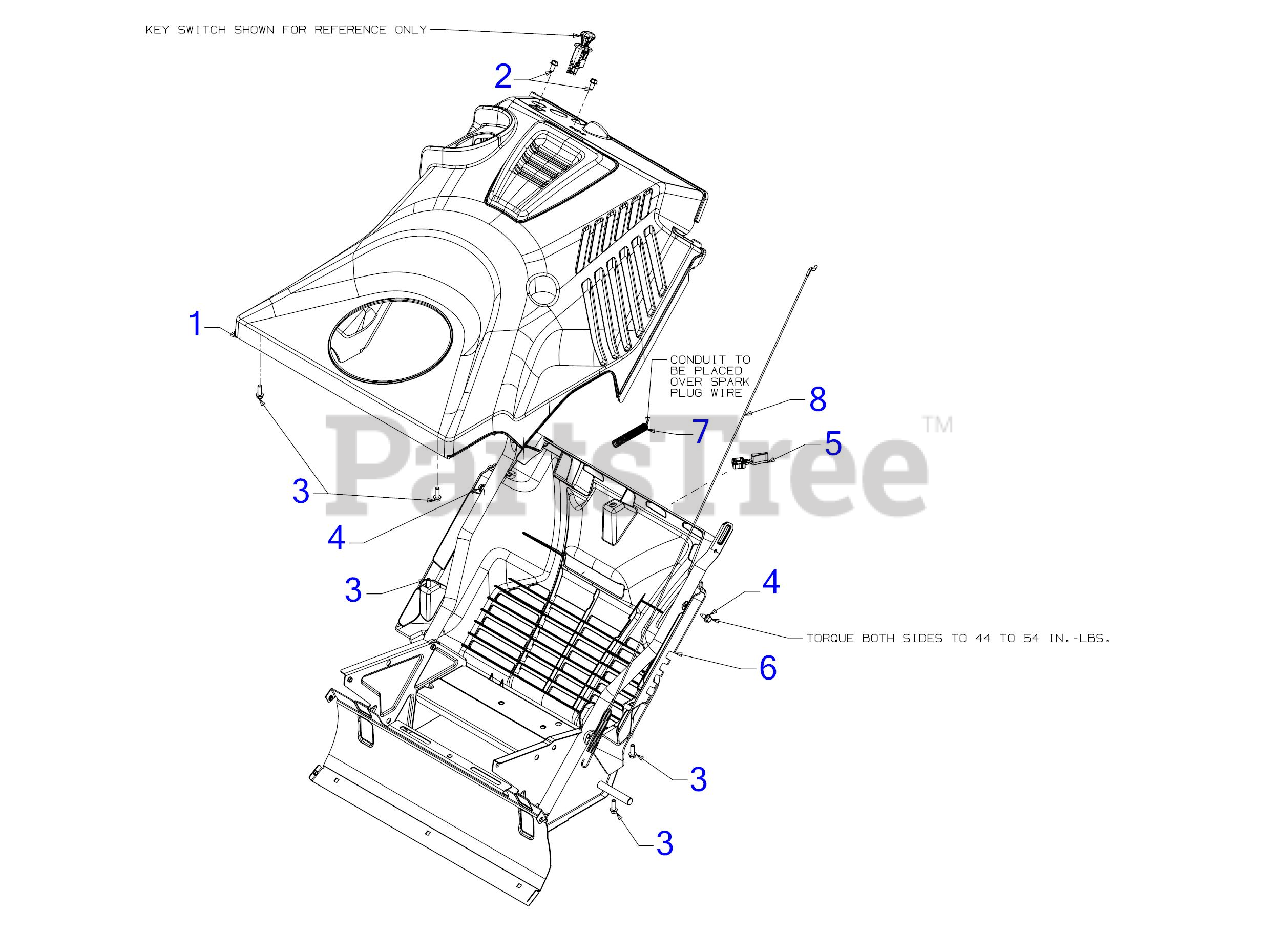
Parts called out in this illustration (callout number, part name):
1	COVER ASSEMBLY
2	HEX SCREW 1/4-15 x .50
3	SCREW 1/4-15 x .750
4	SCREW 1/4-20X.625
5	CHOKE EXTENION LEVER
6	BOTTOM COVER
7	CONVOLUTED CONDUIT
8	AUGER CLUTCH CABLE 37.05"
